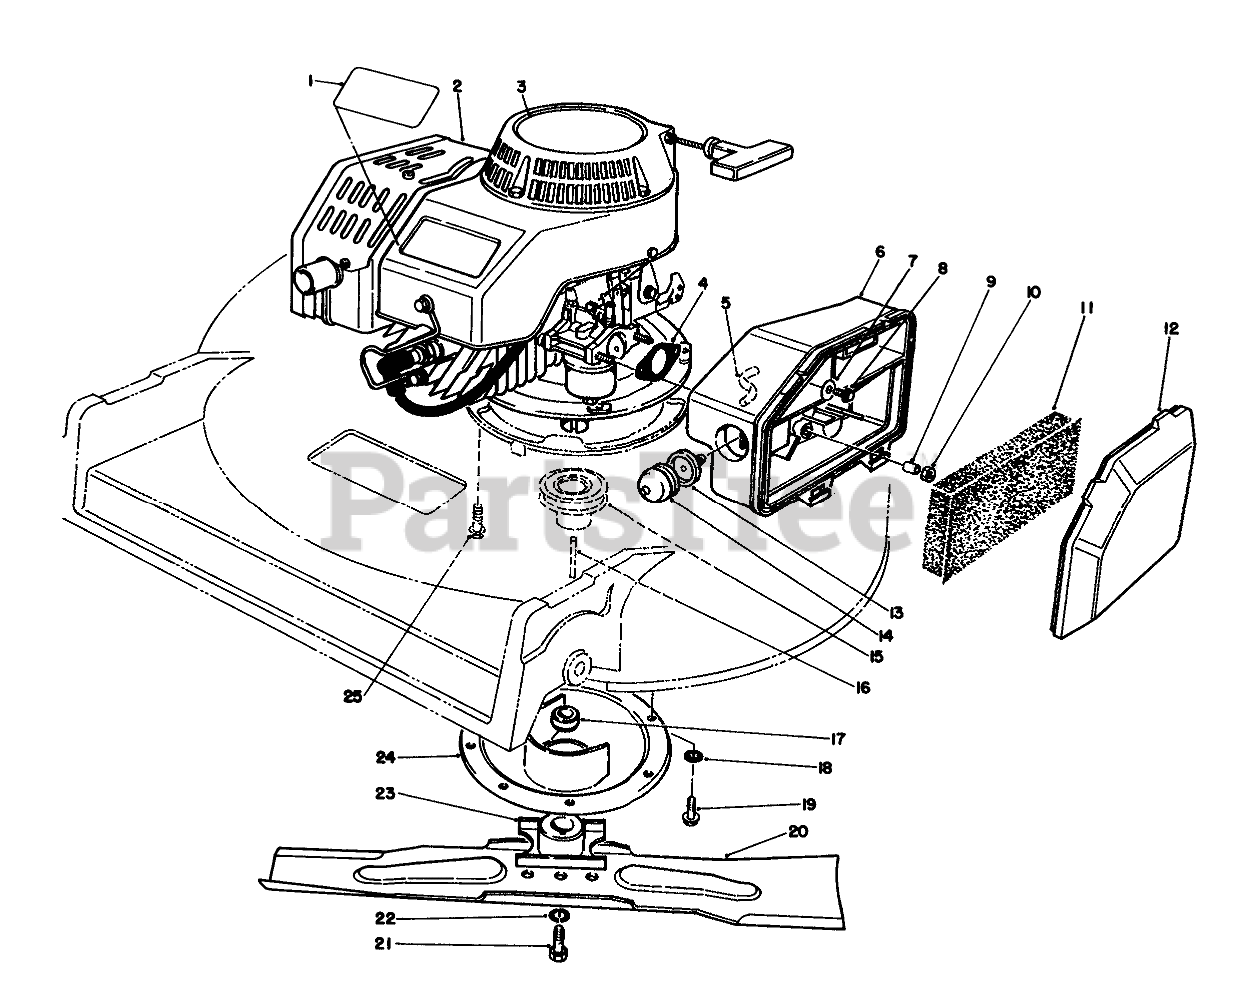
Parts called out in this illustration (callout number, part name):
1	DECAL - PROLINE
2	ENGINE ASM
3	DECAL-2 CYC RECOIL COMM
4	GASKET-AIR CLEANER
5	HOSE-PRIMER
6	BODY-AIR CLEANER
7	WASHER-FLAT
8	SCREW-HH
9	SPACER
11	ELEMENT-AIR CLEANER
12	COVER-AIR CLEANER
13	BODY-PRIMER
14	BULB-PRIMER
15	PULLEY-DRIVER
16	KEY-SQUARE
17	SPACER-BLADE RETAINER
18	WASHER-LOCK, INTERNAL
19	SCREW-HWHTF
20	Key
21	SCREW-BLADE
22	WASHER-LOCK
23	RETAINER-BLADE
24	PROTECTOR-CRANKSHAFT
25	SCREW-HHF
